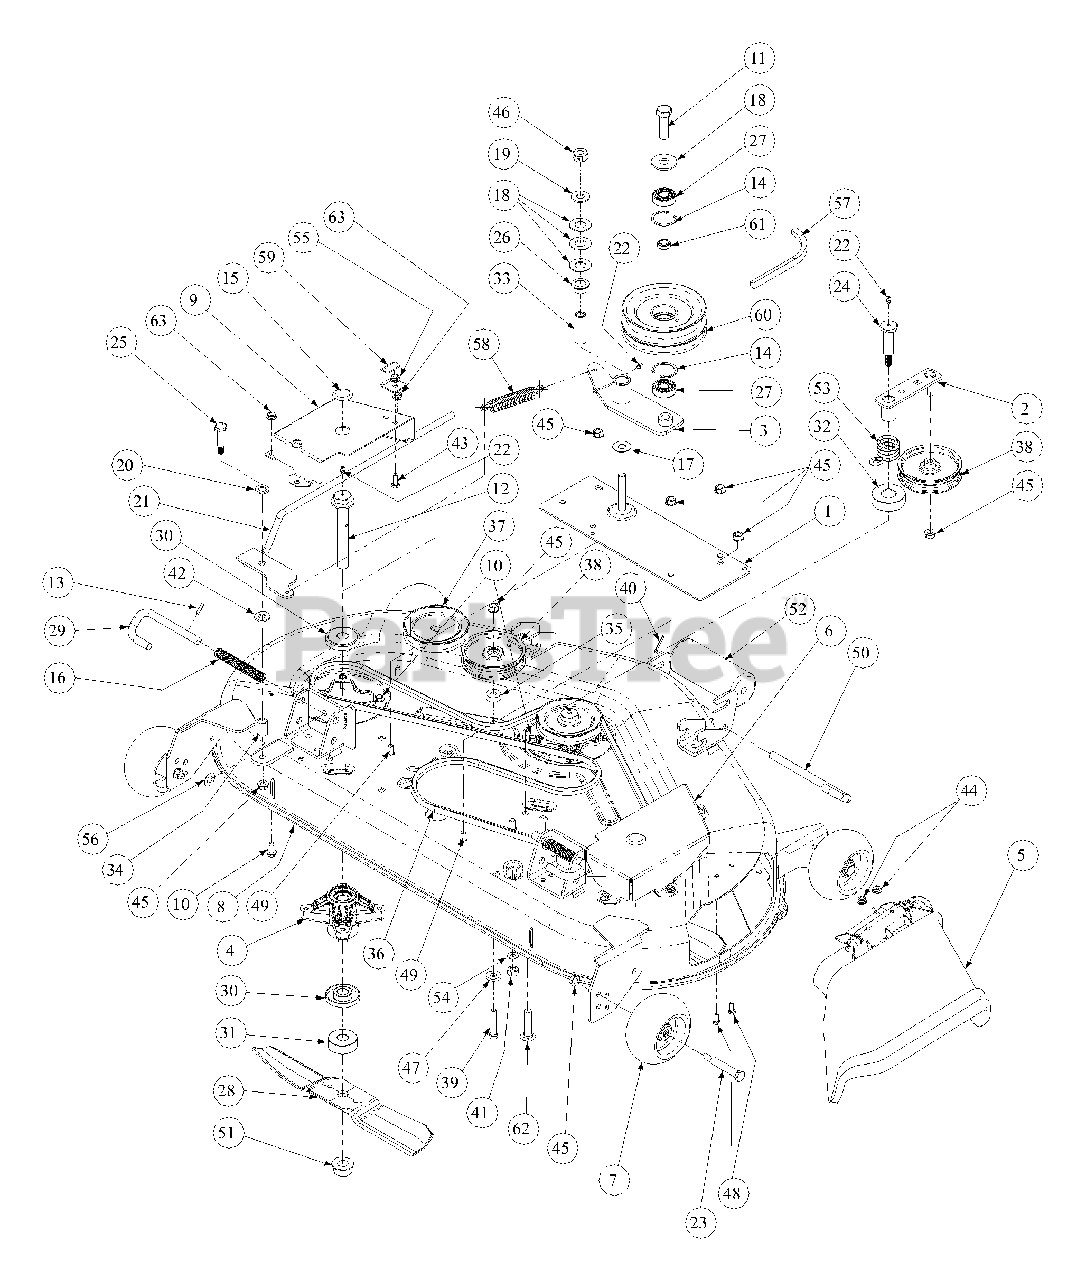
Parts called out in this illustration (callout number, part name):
1	Deck Mounting Plate Assembly
2	Idler Arm Assembly
3	Idler Assembly
4	Spindle Assembly
5	Chute Assembly
6	Belt Cover Right Hand
7	Deck Wheel
8	Deck Assembly 44"
9	Belt Cover Left Hand
10	Self Tapping Screw 5/16-18 x .750
11	Hex Cap Screw 5/8-18 x 4.25
12	Spindle Bolt 3/4-16 x 5.37
14	Internal Snap Ring
15	Button Plug
16	Compression Spring .63 OD x 6.3
17	Flat Washer .531 ID x 1.25 OD
18	Flat Washer .76 ID x 1.49 OD
19	Flat Washer .50 ID x 1.25 OD
20	Flat Washer .536 ID x .93 OD
21	Deck Handle Weldment
22	Grease Fitting
23	Shoulder Screw 1/2 x 2.5
24	Shoulder Screw .68 x 2.11
25	Shoulder Screw .498 x 1.445
26	Flange Bearing .75 ID x .52
27	Bearing .625 ID x 1.574 OD
28	Blade
29	Support Pin
30	Spindle Spacer
31	Blade Spacer
32	Spacer .760 ID x 1.5 OD
33	Spacer .50 OD x .75 ID
34	Spacer .550 ID x .750 OD
35	Spacer .406 ID x 1.0 OD
36	Belt
38	Flat Pulley
39	Hex Cap Screw 3/8-16 x 2.00
40	Cotter Pin .125 Dia x 1.0
41	Nut 7/16-14, Nylock
42	Flat Washer .50 ID x 1.065 OD
43	Hex Cap Screw 5/16-18 x .75
44	Nut, 1/4-20, hexflange Lock
45	Hex Nut, 3/8-16, Flange Lock
46	Nut, 1/2-20, Center Lock
47	Idler Washer
48	Hex Cap Screw 1/4-20 x .620
49	Carriage Bolt 3/8-16 x .75
50	Roller Pin 1/2 x 7.31
51	Nut, 3/4-16, Hex Flange
52	Front Roller
53	Idler Torsion Spring
54	Flat Washer, .469 ID x .875 OD x .105
55	Lock Nut 5/16-18 Hex Flange
56	Flat Washer .508 ID x 1.0 OD
57	Belt
58	Extension Spring .865 OD x 4.68
59	Tension Rod Stop Bracket
60	Double Pulley
61	Spacer .635 ID x .88 OD
62	Carriage Bolt 3/8-16 x 1.50
63	Hex Nut, 5/16-18
